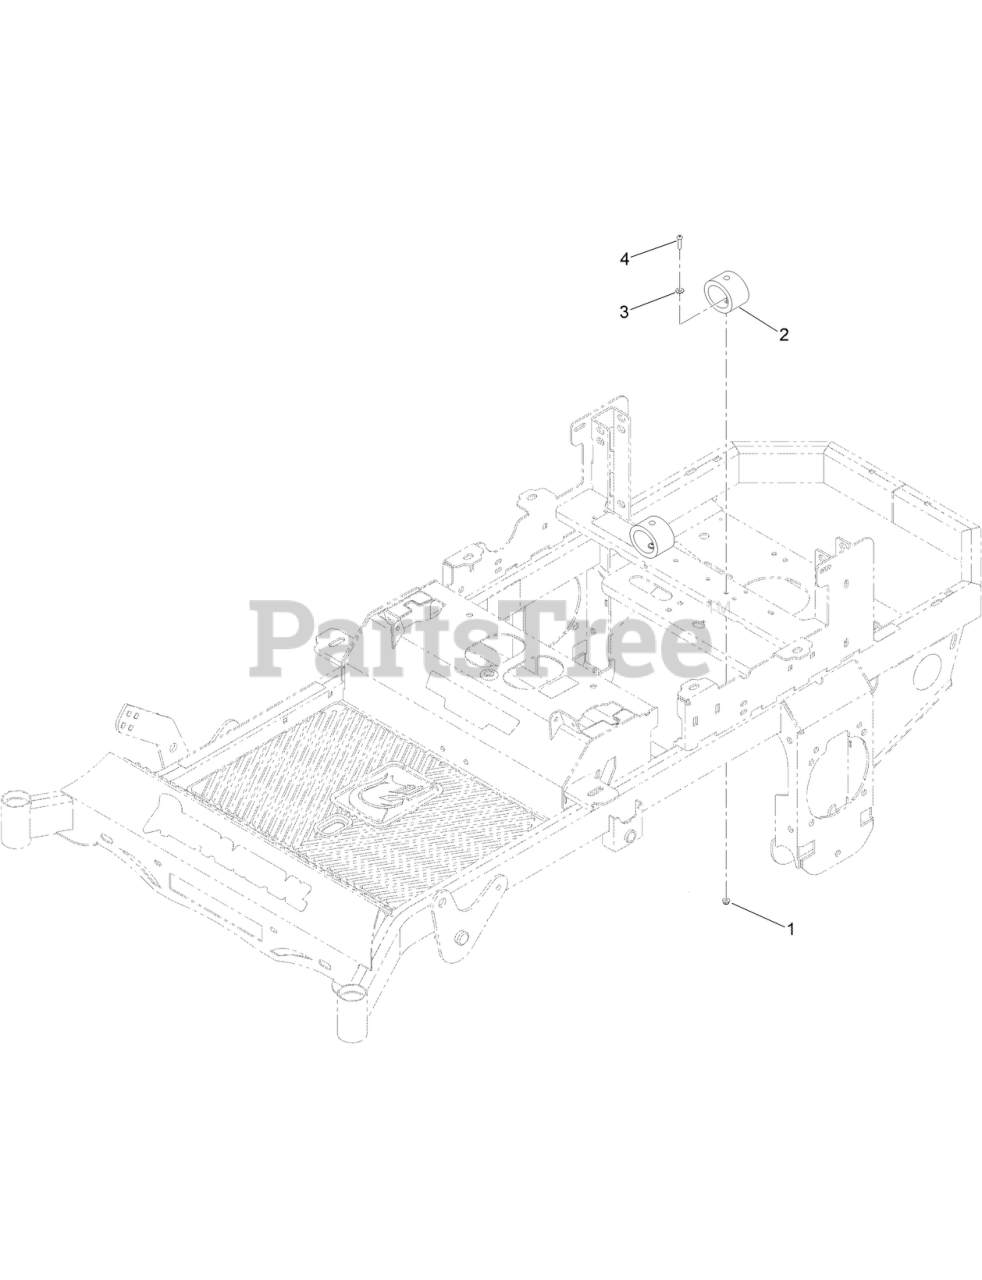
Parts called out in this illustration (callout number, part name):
1	NUT-HF
2	1/4-20 X 1 BUTTON SOCKET C/S 18-8 SS
3	SEAT RR SUSP ELASTOMER
4	WASHER-FLAT
